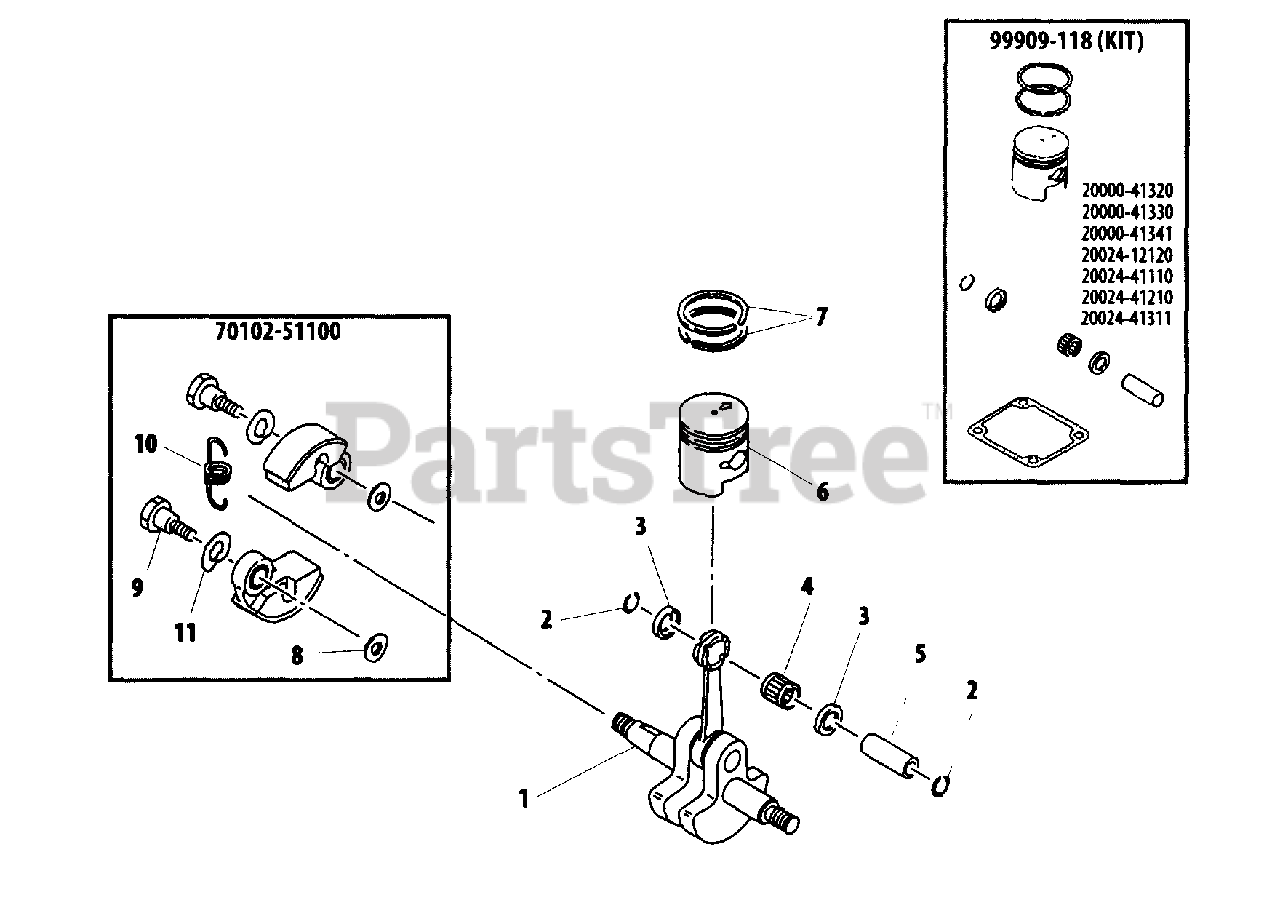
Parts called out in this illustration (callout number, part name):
1	CRANKSHAFT ASSY
2	RING, RETAINING
3	WASHER, THRUST - 9
4	BEARING, NEEDLE
5	PIN, PISTON
6	PISTON
7	RING, PISTON
8	WASHER - 6
9	BOLT, CLUTCH
10	SPRING, CLUTCH
11	WASHER - SPRING
70102-51100	CLUTCH SHOE ASSY
99909-118	PISTON ASSY
